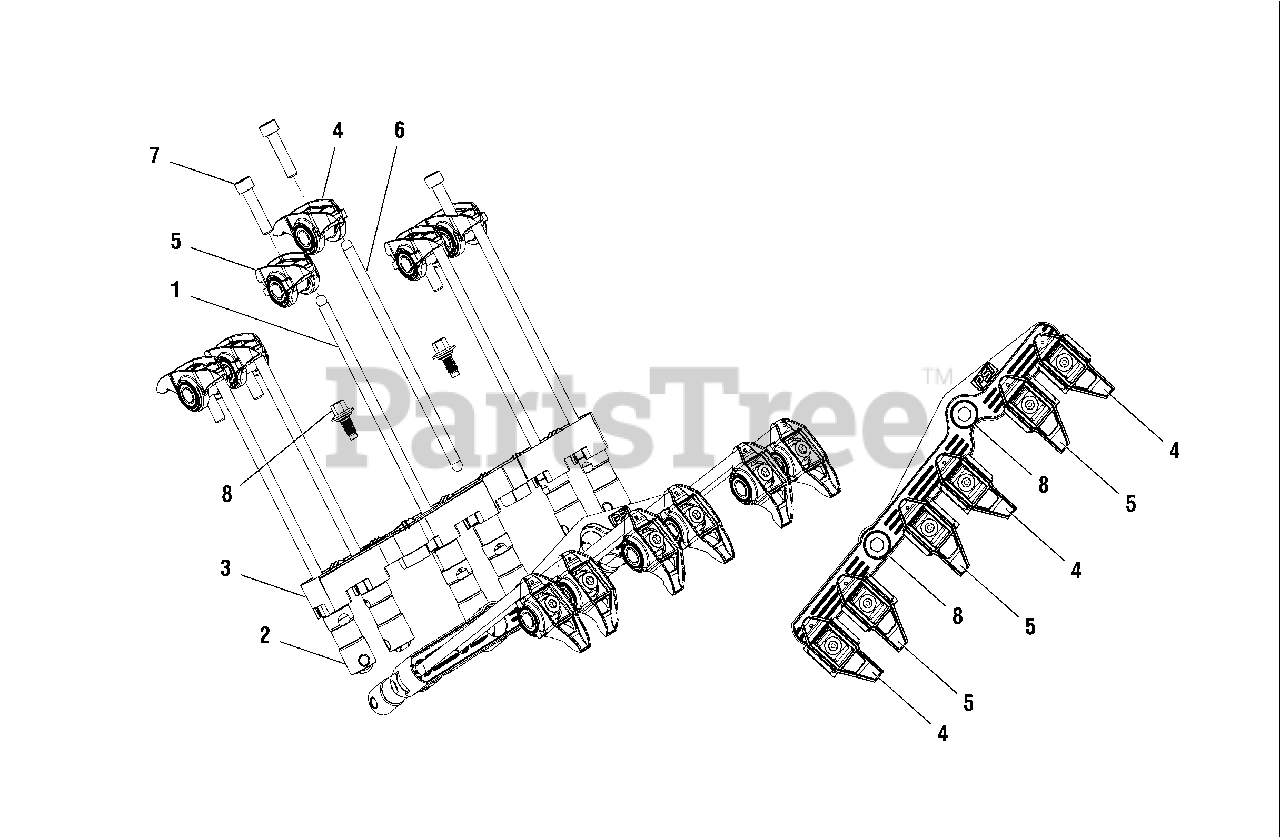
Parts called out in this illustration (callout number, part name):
1	PUSH ROD (INTAKE)
2	LIFTER
3	LIFTER, BUCKET
4	ROCKER ARM ASSEMBLY
5	ROCKER ARM
6	PUSH ROD (EXHAUST)
7	BOLT, ROCKER VALVE
8	BOLT, LIFTER BUCKET
